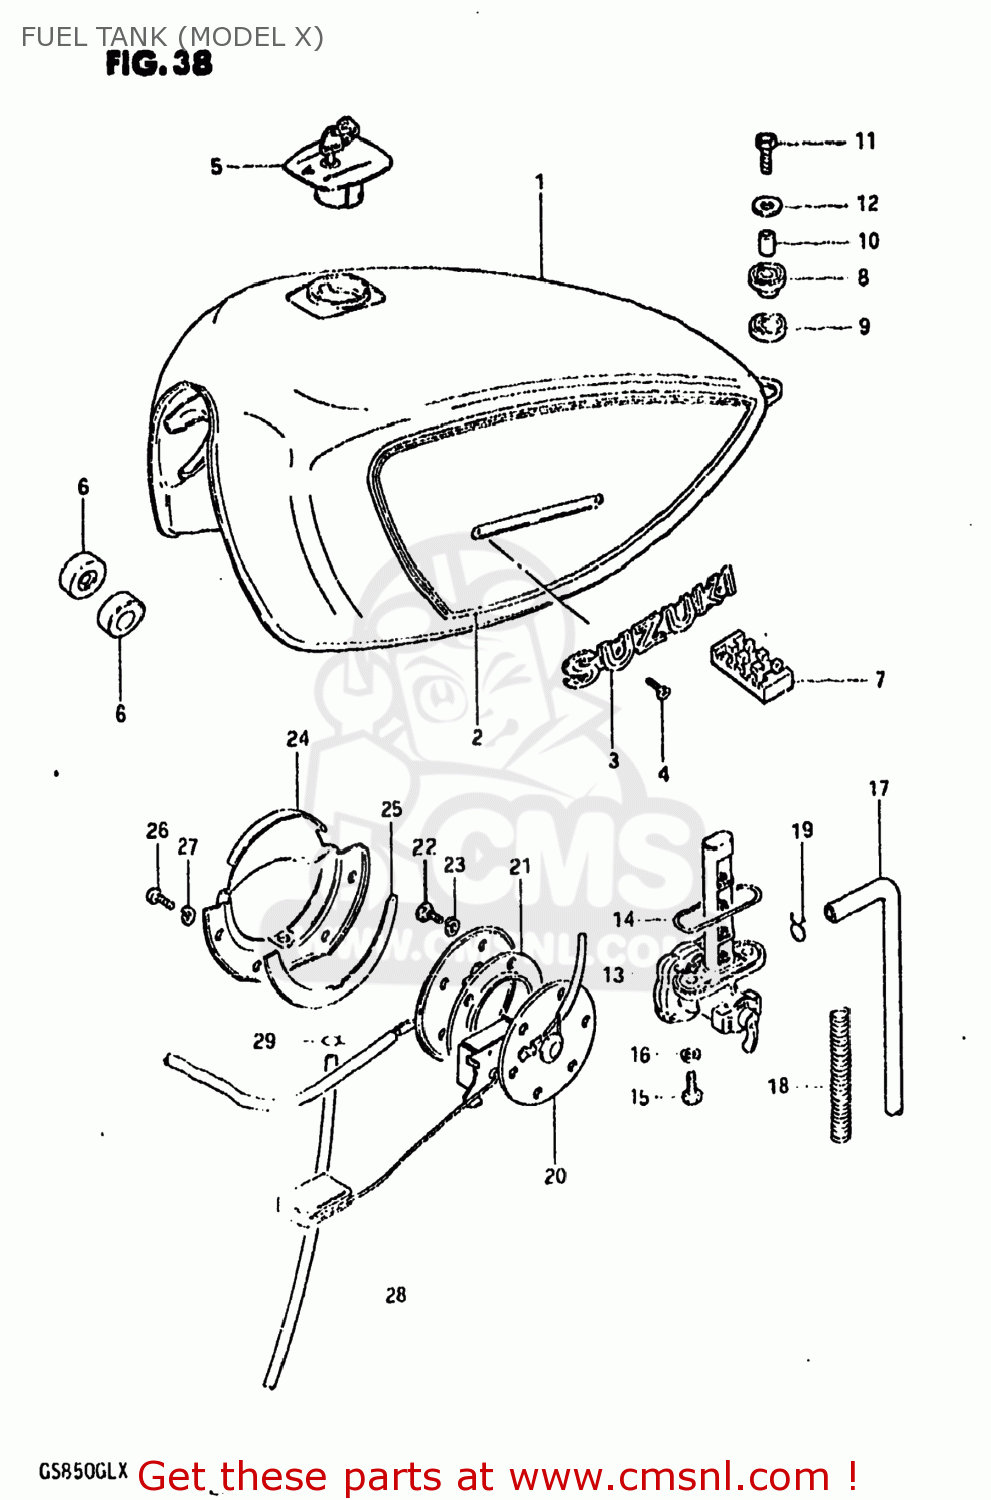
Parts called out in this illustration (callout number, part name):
1	TANK ASSEMBLY,FUEL
2	TAPE SET,FUEL TANK
3	EMBLEM,FUEL TANK
4	SCREW 3X6
5	CAP SET,FUEL TANK
6	CUSHION
7	CUSHION,FUEL TANK CTR
8	CUSHION
9	CUSHION
10	SPACER
11	BOLT
12	WASHER (6.5X24X1.6)
13	COCK ASSEMBLY,FUEL
14	O RING
15	BOLT(6X20)
16	GASKET
17	HOSE
18	SPRING
19	CLIP
20	GAUGE ASSEMBLY,FUEL LEVEL
21	GASKET,FUEL LEVEL GAUGE (NAS)
22	BOLT
23	LOCK WASHER
24	PLATE,FUEL DRAIN
25	GASKET,FUEL DRAIN PLATE (NAS)
26	SCREW
27	LOCK WASHER
28	HOSE
29	CLIP
